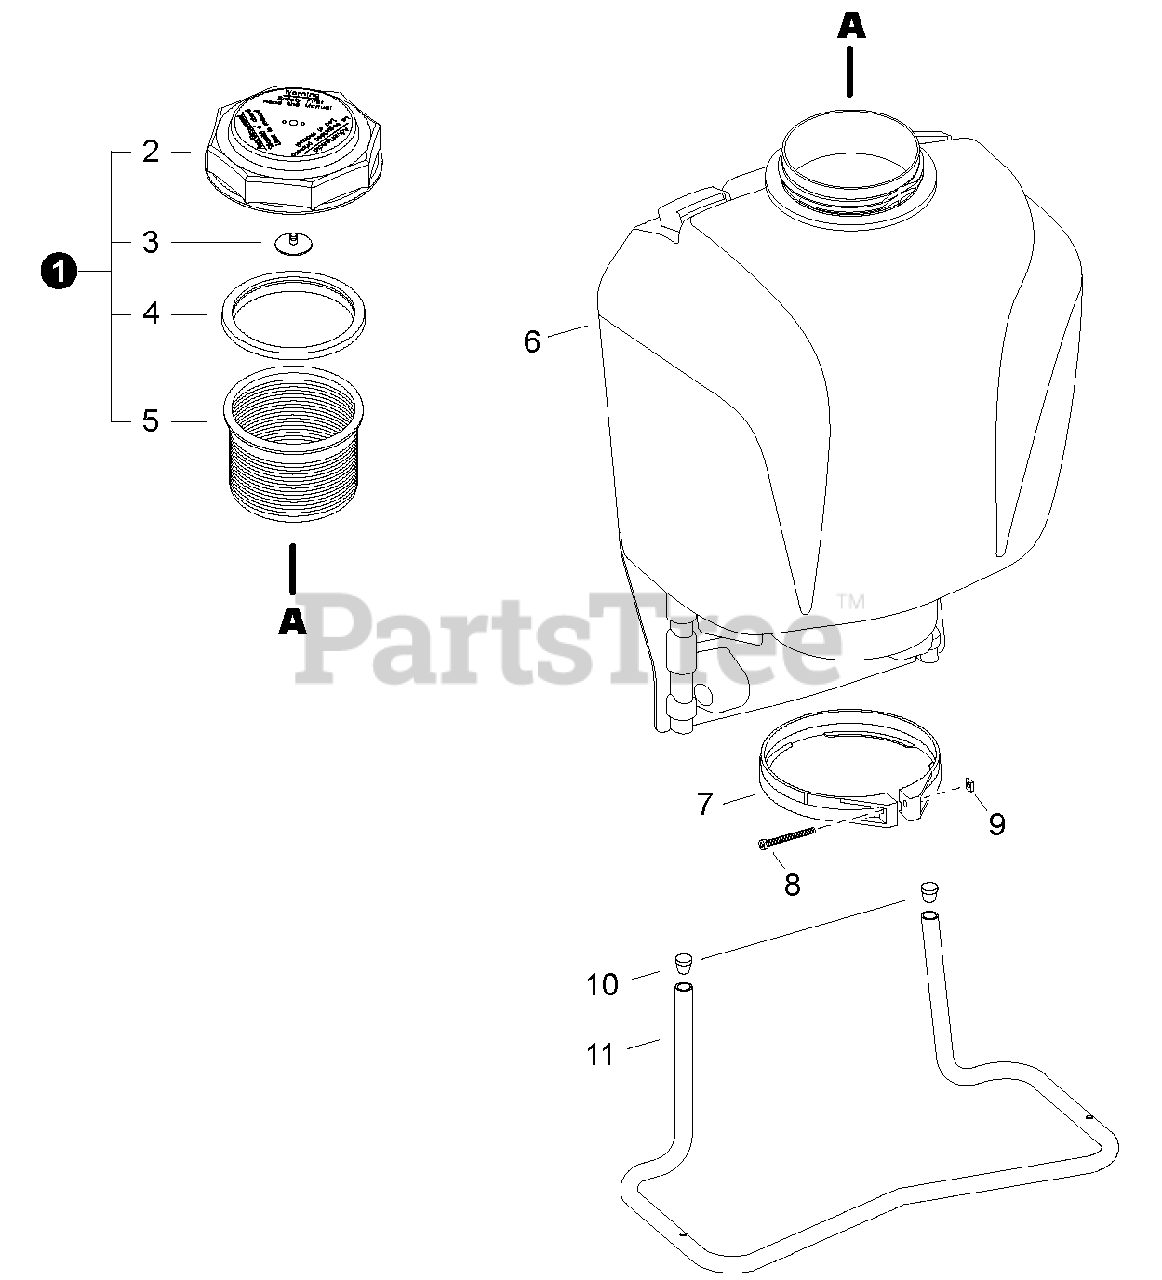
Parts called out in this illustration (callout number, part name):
1	CAP KIT, TANK
2	CAP, TANK
3	VALVE, CHECK - CAP
4	GASKET, BASKET
5	BASKET, FILTER
6	TANK, SPRAYER
7	CLAMP, PUMP
8	SCREW, CLAMP
10	CAP, BASE
11	BASE, TANK
